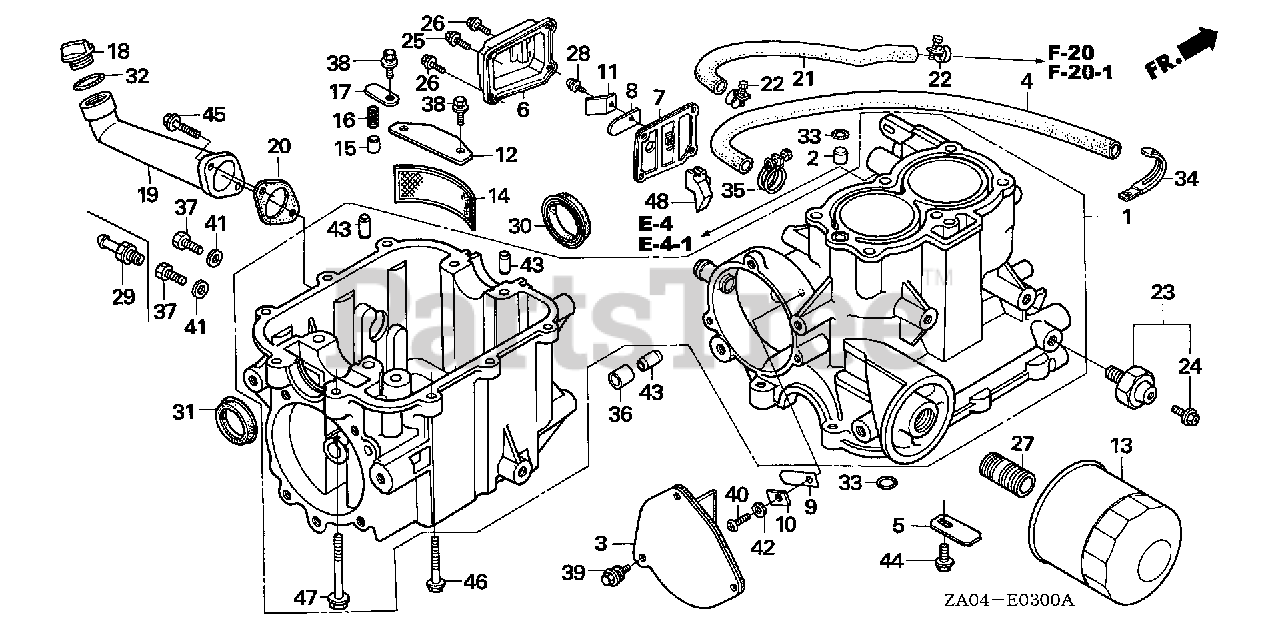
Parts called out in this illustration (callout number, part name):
1	CYLINDER ASSY.
2	ORIFICE, OIL CONTROL
6	COVER, BREATHER
7	PLATE, BREATHER
8	PLATE, VALVE
11	STOPPER, VALVE
12	PLATE, OIL FILTER
13	FILTER, OIL
14	SCREEN, OIL FILTER
15	VALVE, CHECK
16	SPRING, VALVE
17	PLATE, VALVE
18	CAP, OIL
19	PIPE, OIL FILLER
20	GASKET, OIL PIPE
21	HOSE, WATER (LOWER)
22	CLIP, WATER HOSE
23	SWITCH, OIL PRESSURE
24	BOLT-WASHER (4X8)
25	BOLT, FLANGE (6X12) (CT200)
26	BOLT, FLANGE (6X14)
27	PIPE, OIL PASSAGE
28	SCREW-WASHER (5X8)
29	PLUG, OIL DRAIN
30	OIL SEAL (33X48X7)
31	OIL SEAL (30X44X7)
32	O-RING (26X2.7)
33	O-RING (10.8X2.4) (ARAI)
34	CLIP, WIRE
37	BOLT, DRAIN PLUG (12MM)
38	BOLT-WASHER (6X12)
41	WASHER, DRAIN PLUG (12MM)
43	PIN A, DOWEL (10X16)
45	BOLT, FLANGE (6X16)
46	BOLT, FLANGE (6X28)
47	BOLT, FLANGE (8X55)
48	GUARD, BREATHER
